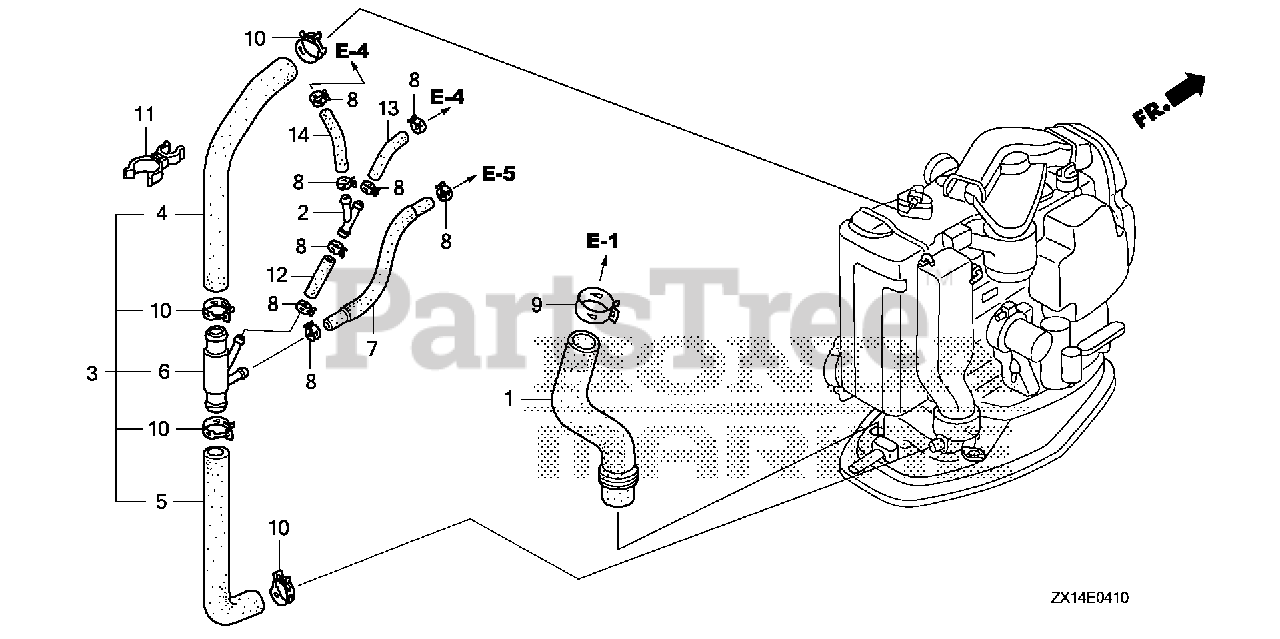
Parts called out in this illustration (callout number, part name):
2	JOINT, FUEL TUBE
3	TUBE, WATER RELIEF
4	TUBE A, WATER RELIEF
5	TUBE B, WATER RELIEF
6	JOINT, FOUR-WAY
7	TUBE E, WATER
8	CLAMP, TUBE (D10.5) (ENGINE NO.)
9	CLAMP, TUBE (D32.5)
10	CLAMP, TUBE (D25.0)
11	CLAMP, WATER TUBE
12	BULK HOSE, VACUUM (7X3000) (7X550)
13	BULK HOSE, VACUUM (7X3000) (7X550)
14	BULK HOSE, VACUUM (7X3000) (7X550)
